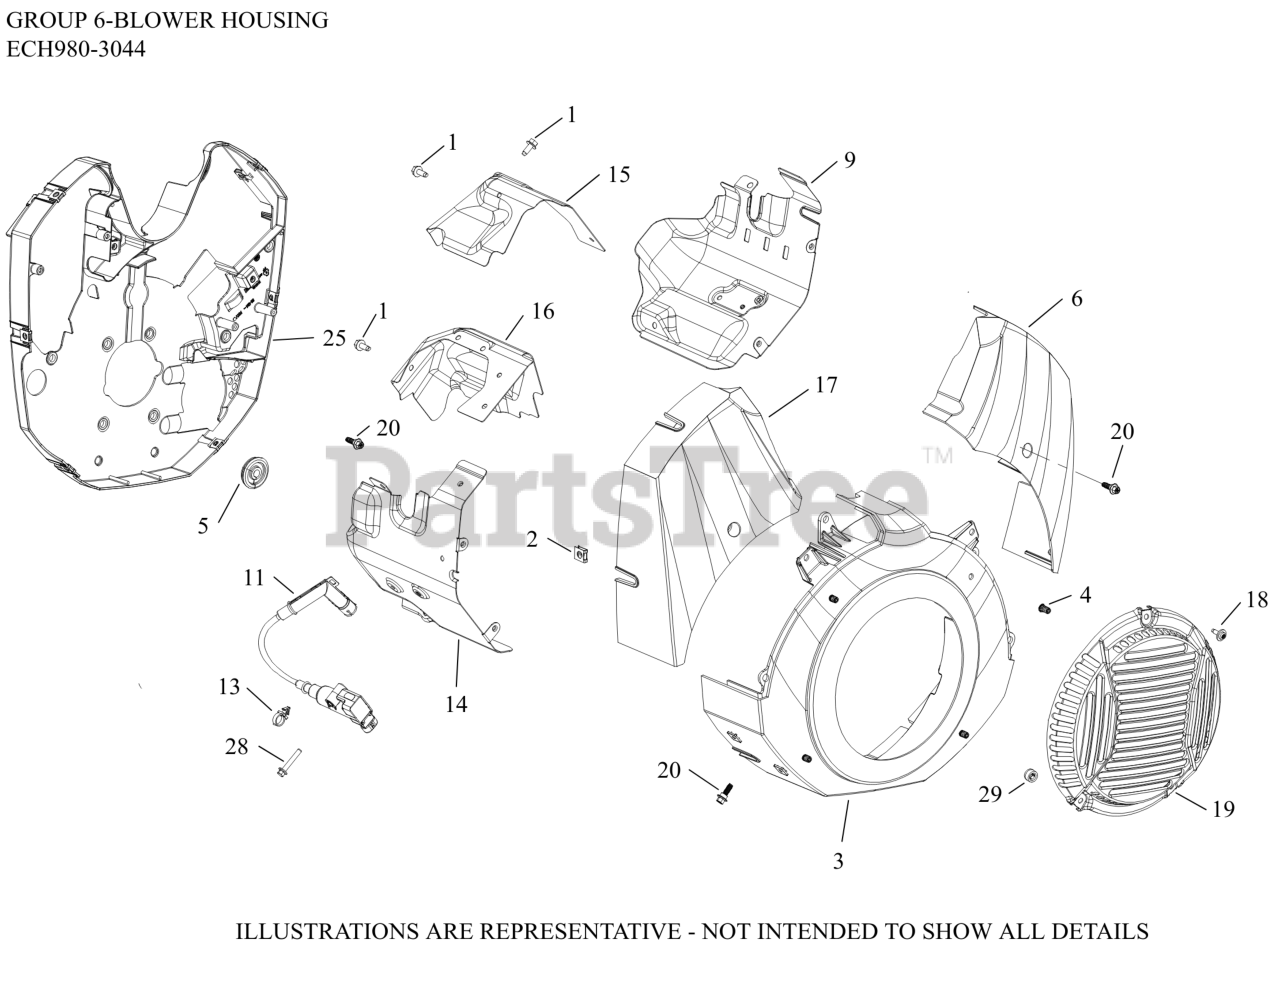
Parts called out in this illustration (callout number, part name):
1	SCREW, THREAD FORMING
2	CLIP, BAFFLE MOUNTING
3	KIT, BLOWER HOUSING
4	INSERT, THREADED (M5)
5	CGROMMET, WIRING HARNESS
6	SHROUD, #1 CYLINDER
9	BAFFLE, BARREL (#1 CYL)
11	COIL, IGNITION - EFI (RFI/EMC)
14	BAFFLE, BARREL (#2 CYL)
15	BAFFLE, VALLEY #1 CYLINDER
16	BAFFLE, VALLEY #2 CYL-USE 62 063 40-S
17	SHROUD, #2 CYLINDER
18	SCREW, SEMS
19	GUARD, GRASS SCREEN (METAL)
20	SCREW, SHD THD FRM
25	SHROUD AND CLIP ASSEMBLY
28	SCREW, HEX FLANGE
